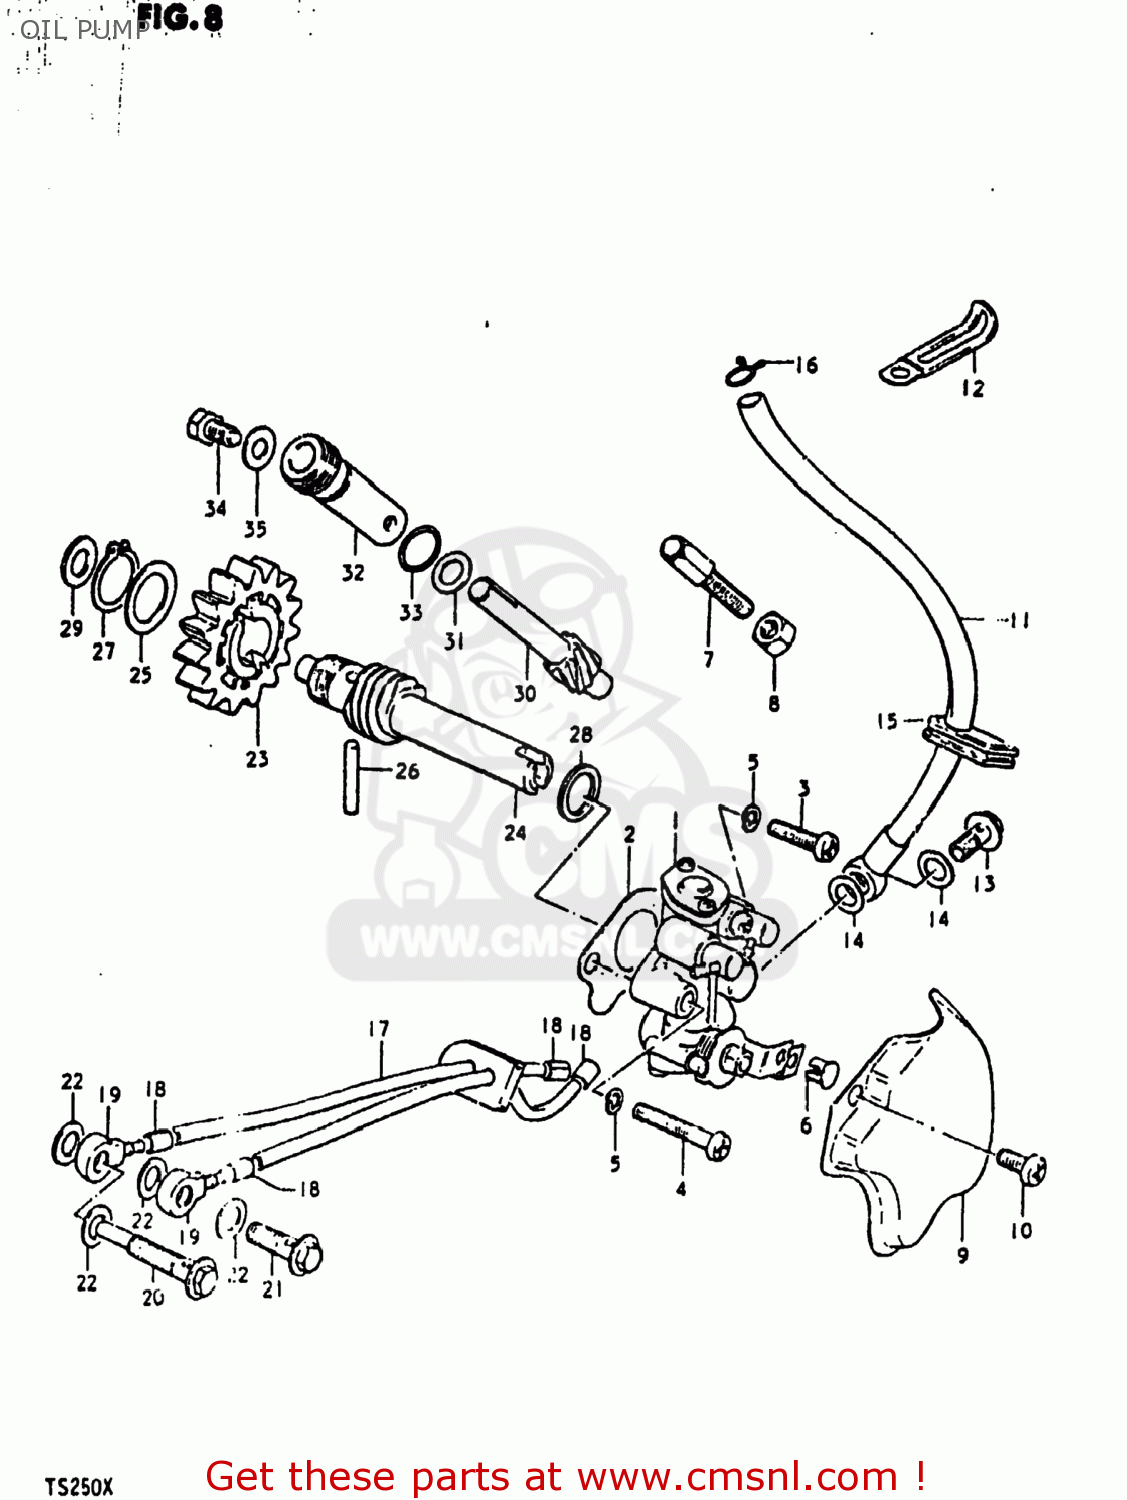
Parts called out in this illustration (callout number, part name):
1	PUMP ASSEMBLY,OIL
2	GASKET,OIL PUMP (NAS)
3	SCREW
4	SCREW
5	LOCK WASHER
6	TERMINAL,CABLE
7	BOLT
8	NUT
9	CAP,OIL PUMP INSPECTION
10	SCREW
11	HOSE,OIL NO.1
12	CLAMP
13	UNION BOLT
14	GASKET(6.2X11X1).2 (NAS)
15	GROMMET
16	CLIP
17	HOSE,OIL NO.2
18	CLIP
19	UNION
20	UNION
21	UNION BOLT
22	GASKET(6.2X11X1).2 (NAS)
23	GEAR,OIL PUMP DRIVE
24	SHAFT,OIL PUMP IDLE GEAR
25	WASHER, INNER
26	ROLLER(4X23.8)
27	CIRCLIP
28	WASHER
29	THRUST WASHER
30	GEAR,TACHOMETER DRIVEN
31	WASHER(8X13.7X1)
32	SLEEVE,TACHOMETER DRIVE
33	O RING(D:1.3,ID:9.6)
34	BOLT
35	WASHER
